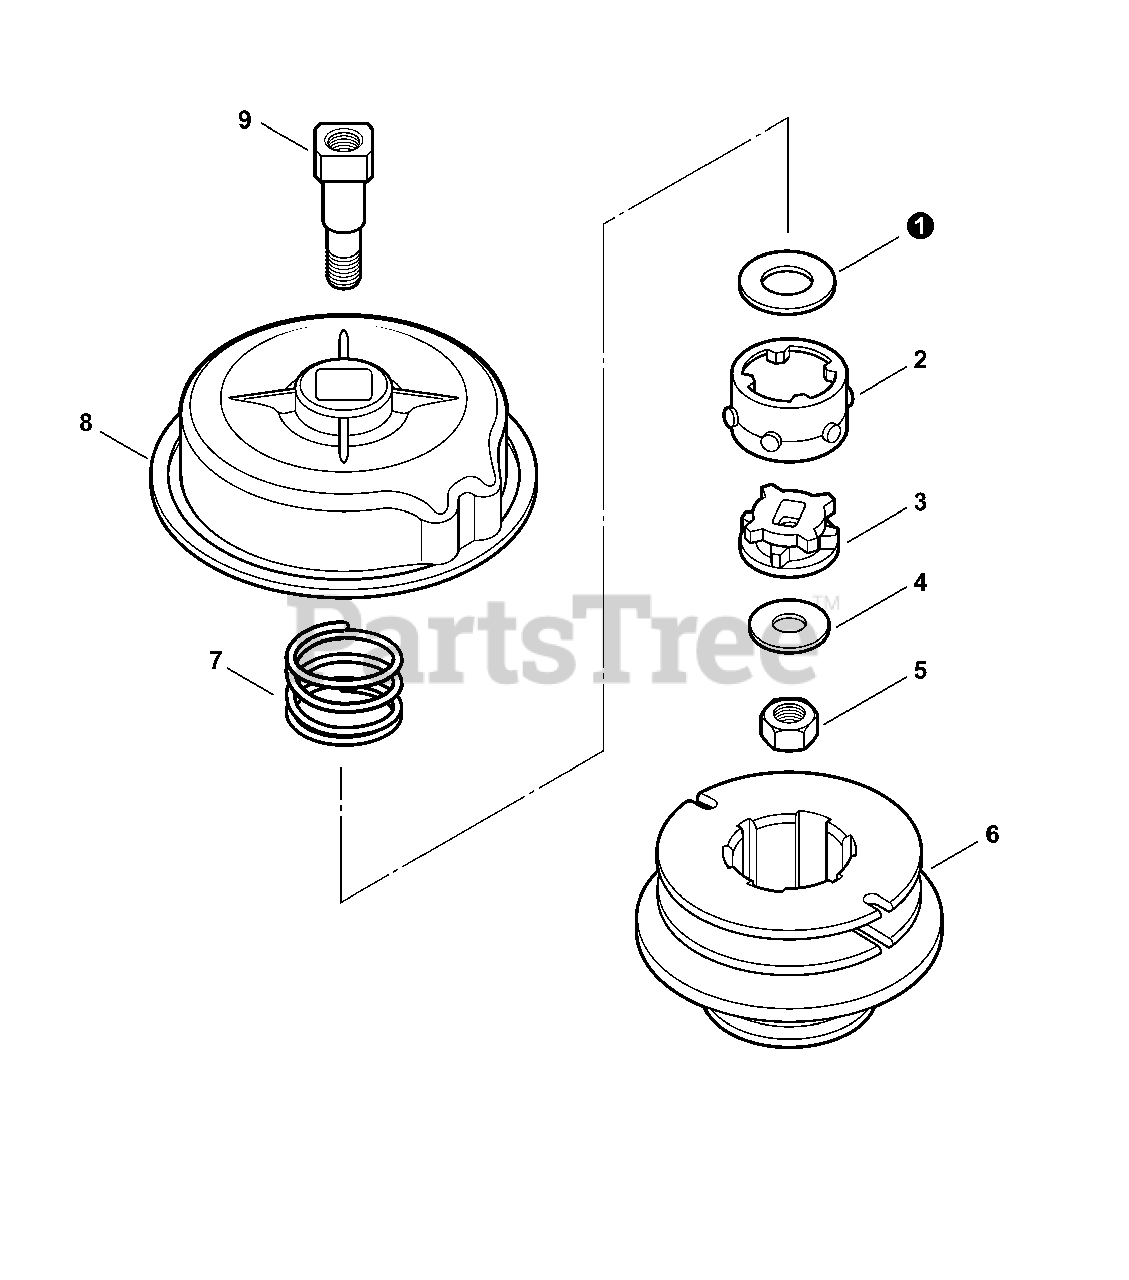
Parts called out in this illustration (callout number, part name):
2	DRIVER, OUTER
3	CAM, INNER
5	LOCKNUT
8	HOUSING
9	BOLT, SHAFT - 10
